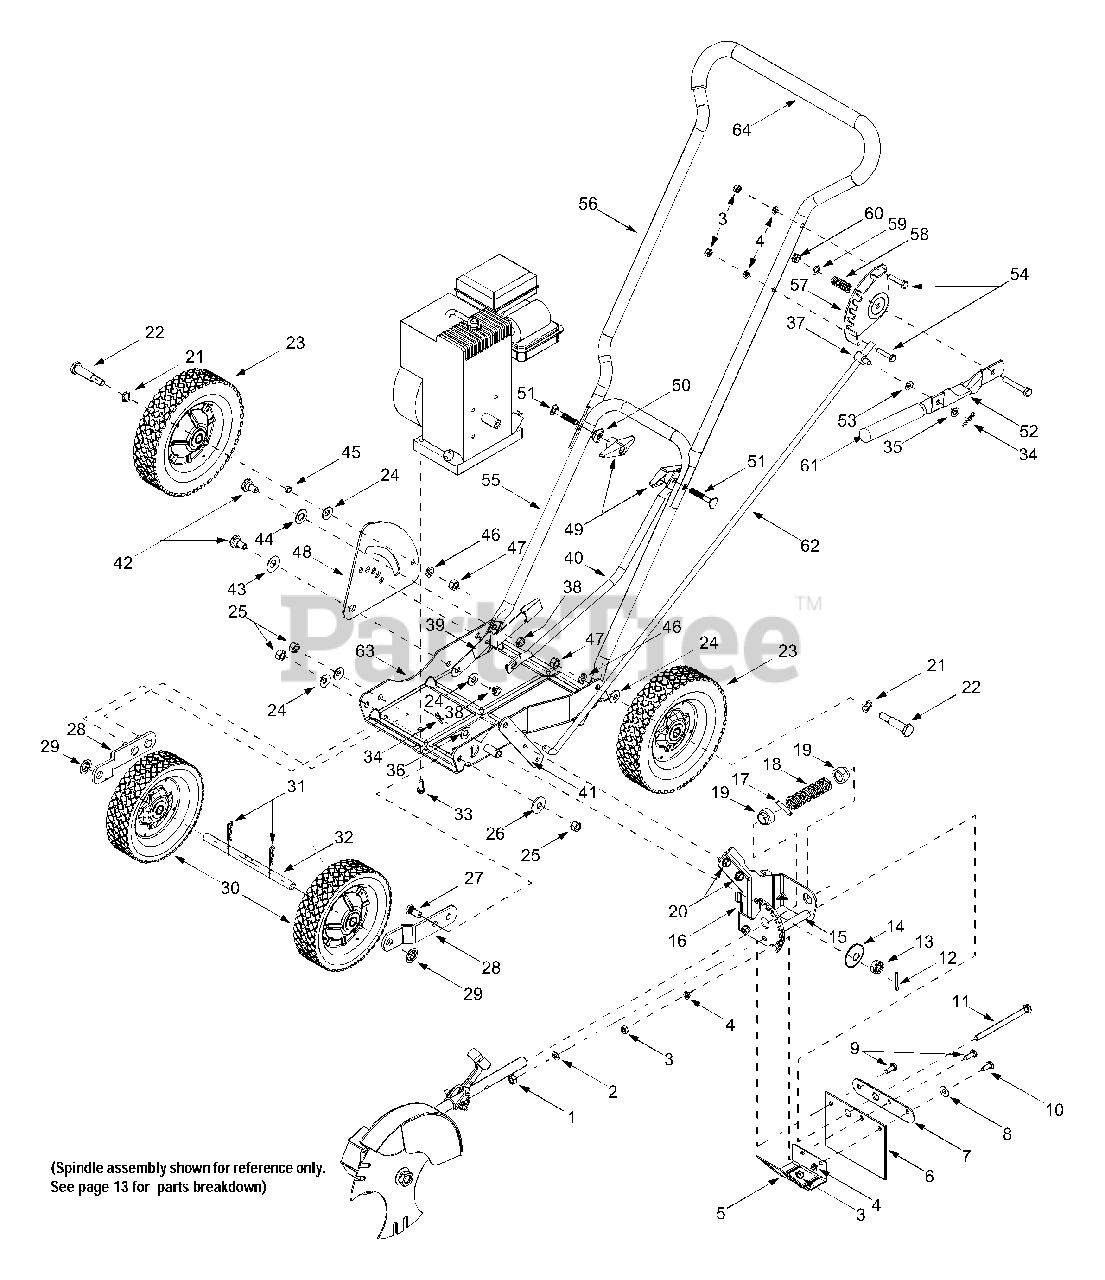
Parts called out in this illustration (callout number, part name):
1	Hex Nut, 5/16-18
2	Lock Washer, 5/16
3	Hex Nut, 1/4-20
4	Lock Washer, 1/4
7	Flap Bracket, 1.12 x 5.5
8	Flat Washer, .283 x .75 x .030
9	Hex Screw w/ Nose, 1/4-20 x .85
10	Hex Screw, 1/4-20 x .62
11	Hex Screw, 5/16-18 x 4.5
12	Cotter Pin, 1/8 x 1.0
13	Slotted Hex Nut, 1/2-20
14	Sphere Washer, .531 x 1.6 x .045
15	Spacer, .38 x .50 x 3.75
18	Compression Spring
19	Shoulder Spacer, .635 x .620
20	Self-tapping Screw, 5/16-18 x .50
21	Wave Washer, .510 x .75 x .017
22	Shoulder Screw, .498 x 1.45
23	Wheel w/ Ball Bearing, 8 x 1.75
24	Spring Washer, .401 x .871 x .063
25	Hex Nut, 3/8-24
26	Bell Washer, .396 x 1.14 x .095
27	Rd Hd Bolt 3/8-24 x .89
30	Wheel w/ Ball Bearing, 7 x 1.75
31	Internal Cotter Pin, .08 x 1.42
32	Front Axle, .50 x 7.98
33	Self-tapping Screw, 3/8-16 x 1.0
34	Internal Cotter Pin, .072 x 1.0
35	Flat Washer, .330 x .630 x .0635
36	Flat Washer, .406 x .810 x .051
37	Adjustment Ferrule
38	Center Lock Nut, 3/8-24
39	Curb Adjustment Lever Assembly
43	Bell Washer, .51 x 1.14 x .040
44	Flat Washer, .51 x 1.0 x .060
45	Spacer, .376 x .625 x .22
46	Lock Washer, 3/8
47	Hex Nut, 3/8-16
50	Saddle Washer, .320 x .93
51	Carriage Bolt, 5/16-18 x .75
53	Spring Washer, .317 x .625 x .099
54	Hex Cap Screw, 5/16-18 x 2.0
58	Compression Spring, .55 x 1.37
59	Flat Washer, .344 x .62 x .030
60	Hex Lock Nut, 5/16-18
61	Foam Grip (Blade Clutch Lever)
62	Clutch Rod, 3/8 x 33.5
